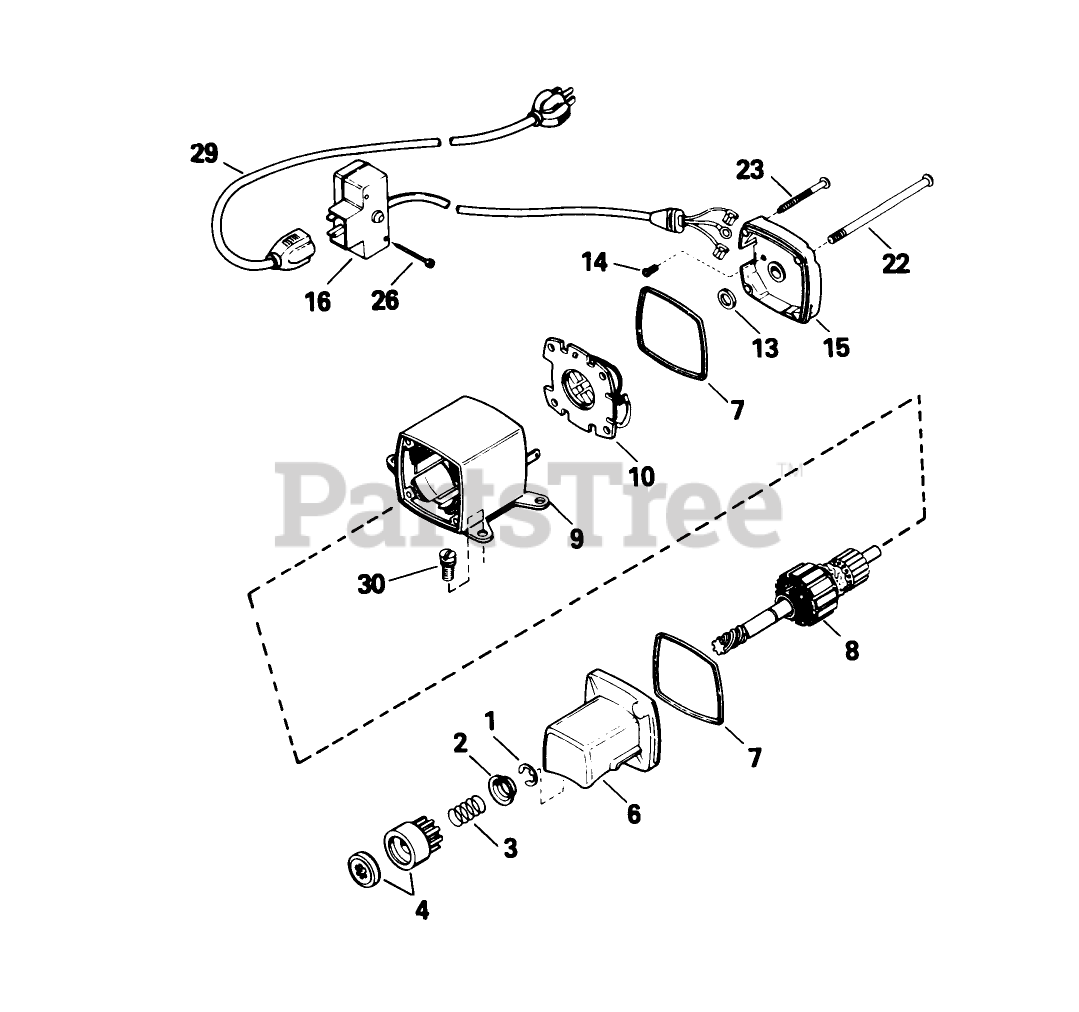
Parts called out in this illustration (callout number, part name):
1	Retainer-Ring
2	Retainer-Spring
3	Spring-Anti Drift
4	Nut Gear
6	Cap Assembly (Incl. Ref. #7)
7	O-Ring
8	Armature
9	Housing Assembly
10	Card ASM
13	Washer-Thrust
14	Screw-Ground
15	Cap Assembly (Incl. Ref. #7)
16	Box Assembly-Switch (Incl. Ref. #26)
22	Bolt-Case
23	Screw-Ground
26	Screw
29	Cord-Extension
30	Screw (T-30, 1/4-20 x 23/32)
